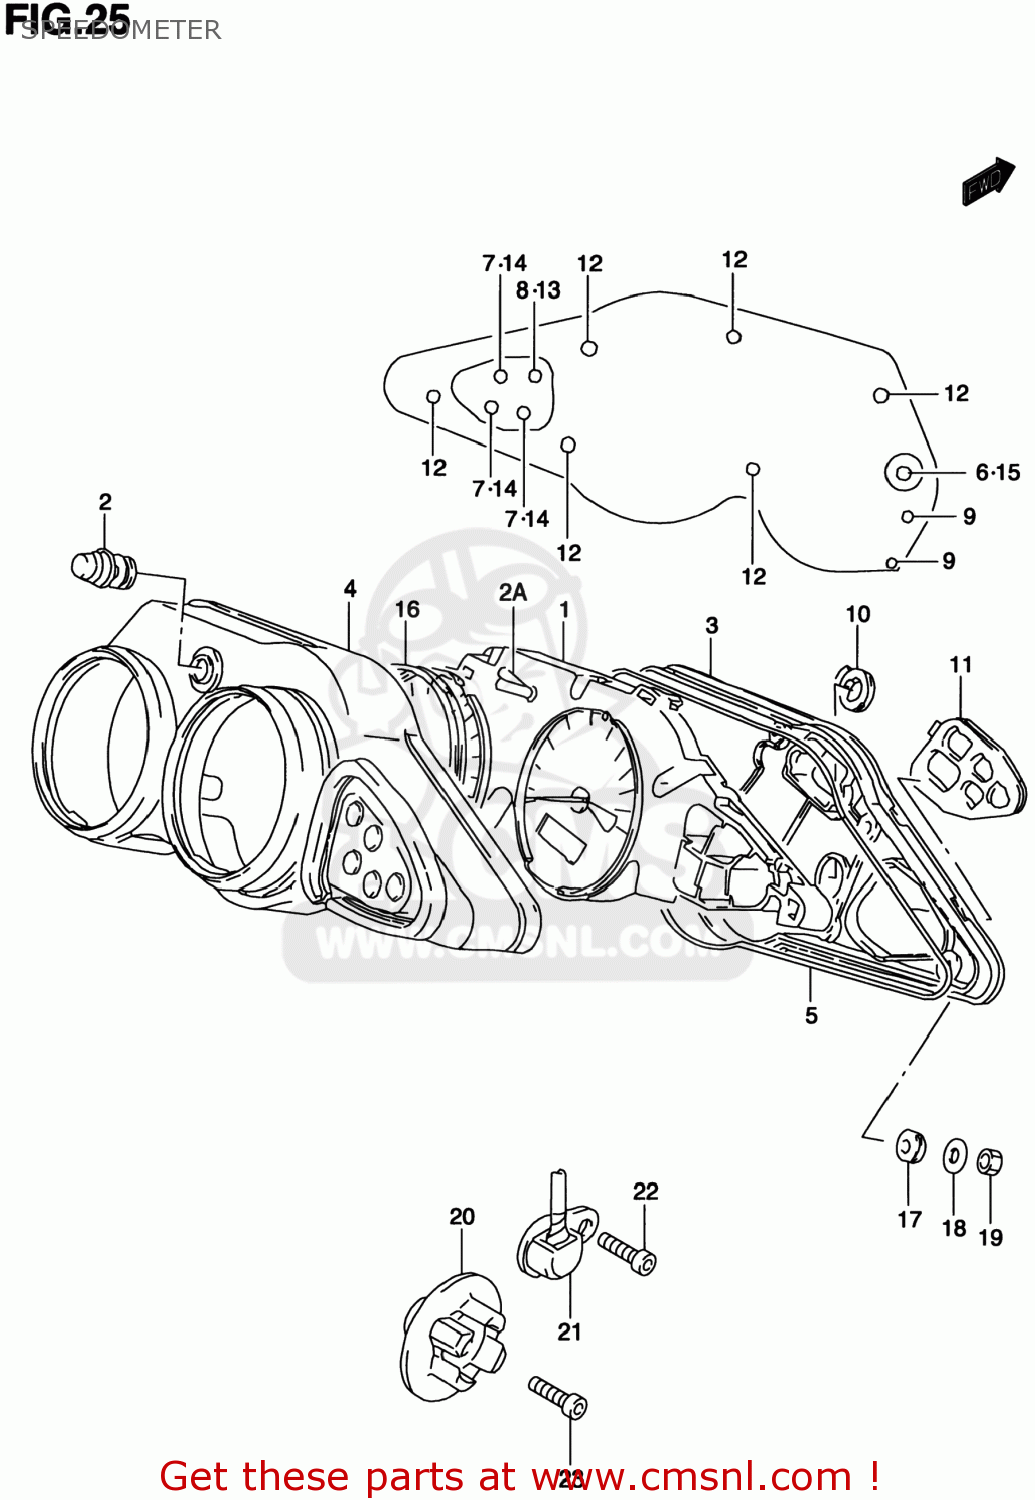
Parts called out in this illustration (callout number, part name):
1	SPEEDOMETER
2	SWITCH,GUM
2A	LEVER
3	CASE ASSEMBLY
4	VISOR
5	GASKET (NAS)
6	SOCKET,BULB
7	SOCKET
8	SOCKET
9	SCREW(4X14)
10	BLIND,CAP
11	BLIND
12	SCREW
13	BULB(12V3W,WB371,T7)
14	BULB(12V1.7W,WB372,T7)
15	BULB(14V,0.84W)
16	CUSHION
17	CUSHION,METER
18	WASHER(5.5X16X1.2)
19	NUT
20	ROTOR,SPEED
21	SENSOR,SPEED
22	BOLT
23	BOLT
